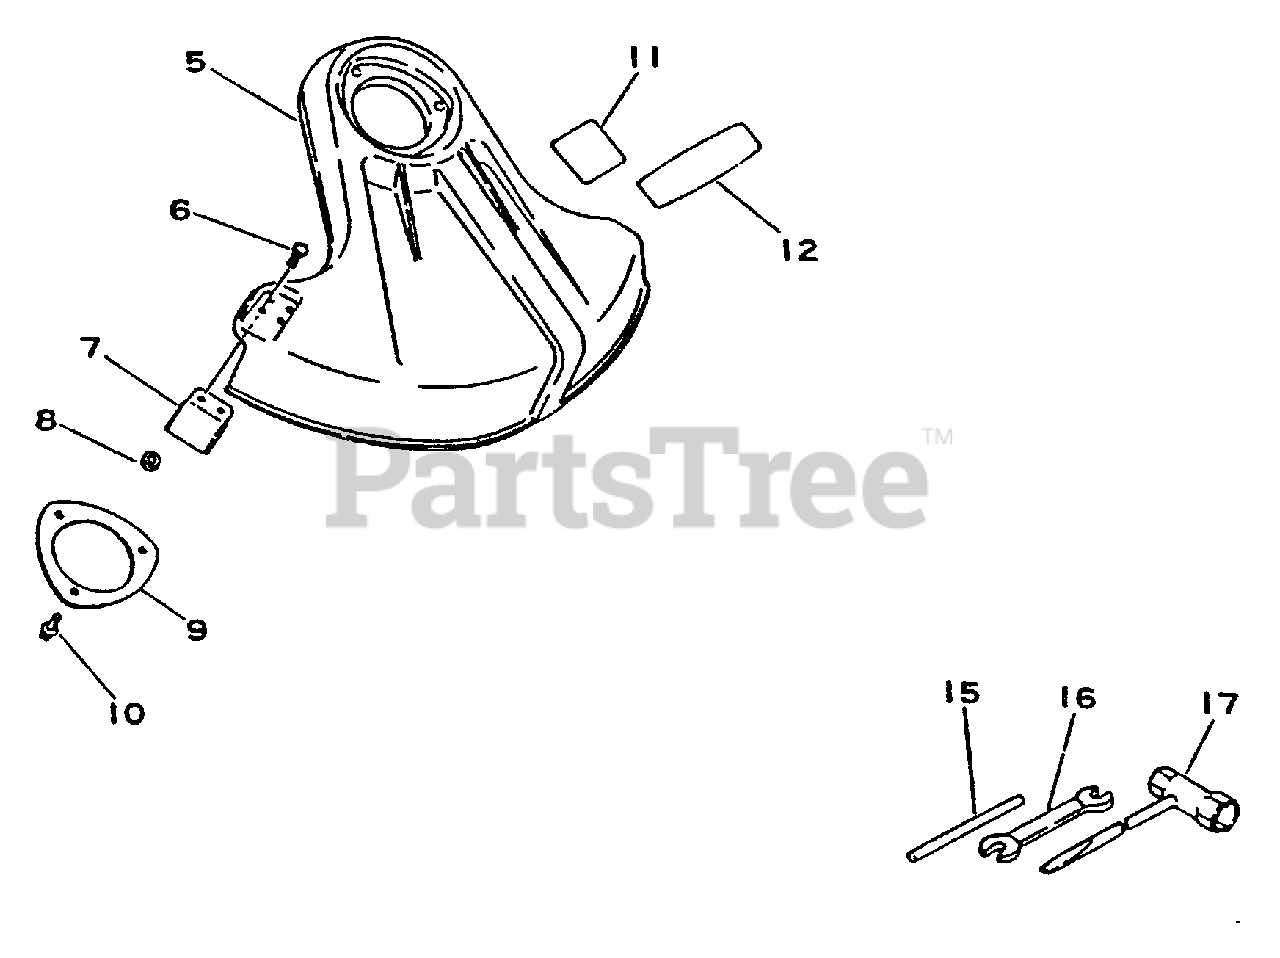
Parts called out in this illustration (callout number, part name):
5	SHIELD
6	SCREW 5×16
7	CUTTER, LINE
8	NUT, HEX M6
9	BRACKET, SHIELD
10	SCREW 5×16
11	LABEL, CAUTION
12	LABEL - ECHO
15	TOOL, LOCKING 5×120 MM
16	SPANNER 8×10
17	T-WRENCH
